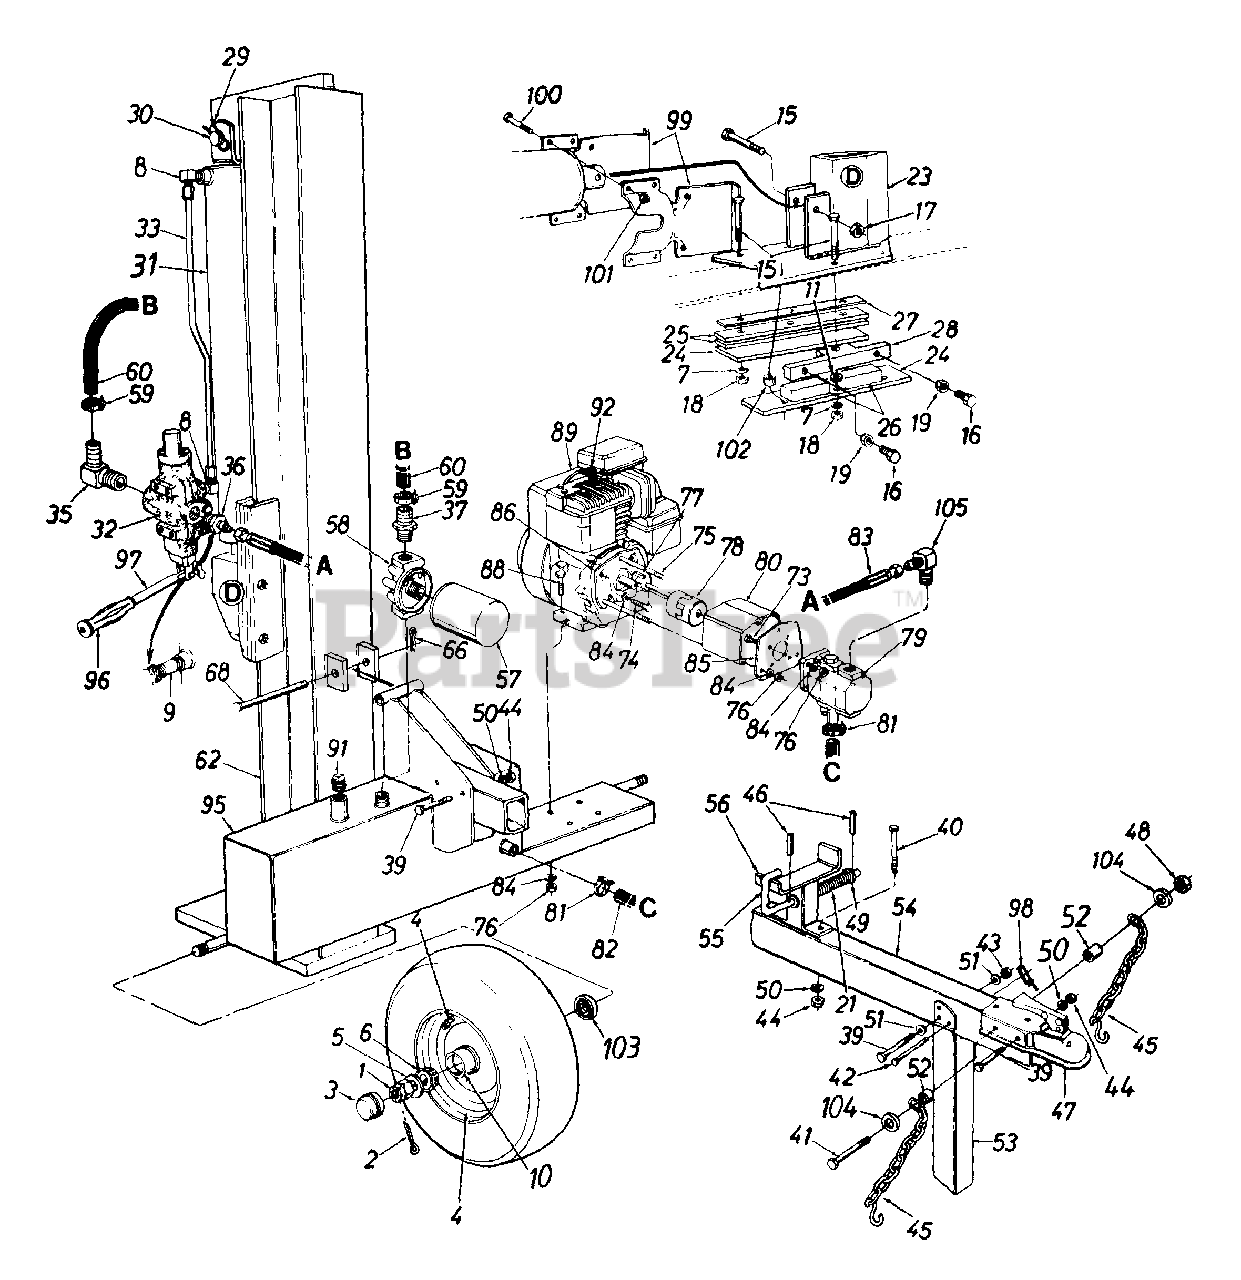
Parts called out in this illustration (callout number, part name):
1	Slotted Nut 3/4-16 Thd.
2	Cotter Pin 5/32" Dia. x 1-1/4" Lg.
3	Hub Cap
5	Fl-Wash..76" I.D. x 1.5" O,D.
6	Bearing Cone
7	L-Wash. 1/2" I.D.
8	90§ Solid Male Adapter
9	Pipe Nipple 1/2 NPT
10	Bearing Cup
11	Fl-Wash..531" I.D. x .94" O.D.
15	Hex Bolt 1/2-20 x 2.75" Lg. (Grade 8)
16	Hex Bolt 3/8-24 x 1.5" Lg.
17	Hex L-Nut 1/2-20 Thd.
18	Hex Nut 1/2-20 Thd.
19	Hex Jam Nut 3/8-24 Thd. (Grade 5)
21	Comp. Spring 4" Lg.
29	External Cotter Pin
30	Cylinder Mounting Pin
33	Metal Pressure Tube
35	Return Elbow
36	Adapter
37	3/4" Hose Barb.
39	Hex Bolt 3/8-16 x 2.75" Lg. (Grade 8)
40	Hex Bolt 3/8-16 x 4" Lg.
41	Hex Bolt 3/8-16 x 4" Lg. (Grade 5)
42	Clevis Pin 5/16 x 2.5" Lg.
43	Hex L-Nut 3/8-16 Thd.
44	Hex Nut 3/8-16 Thd.
45	Chain - Tow Hitch
46	Roll Pin
47	Hitch Coupler
48	Hex Ctr. L-Nut 3/8- 16 Thd.
49	Fl-Wash. 635" I.D. x .93" O.D.
50	L-Wash. 3/8" I.D.
51	Fl-Wash 406" I.D. x .75" O.D.
52	Spacer 3/8" I.D. x 625" O.D.
55	Locking Rod
57	Filter Element
58	Filter Head
59	Hose Clamp 5/8"
60	Return Hose 3/4" I.D x 44" Lg.
68	Hinge Pin 1/2 x 4.8" Lg.
73	Hex Bolt 5/16-24 x 1" Lg.
74	Hex Bolt 5/16-24 x .62" Lg.
75	Hex Bolt 5/16-24 x 4" Lg.
76	Hex Nut 5/16-24 Thd.
77	Sq.-Key 3/16" x 75"
78	Flexible Coupling
79	Gear Pump
80	Coupling Shield
81	Hose Clamp
82	Suction Hose
83	High Pressure Hydraulic Hose 48"
84	L-Wash. 5/16" I.D.
88	Hex Bolt 5/16-24 x 3.75" Lg.
89	Engine
91	L-Vent Pipe Plug
92	Spark Plug Boot
95	Tank Ass'y.
96	Grip
97	Control Handle
98	Spring Pin
101	Hex L-Nut 3/8-16 Thd.
102	Spacer 1/2" I.D. x .68" Lg.
103	Bearing Seal Only
104	Fl-Wash. 3/8" I.D. x .87" O.D.
105	90§ Male Adapter
